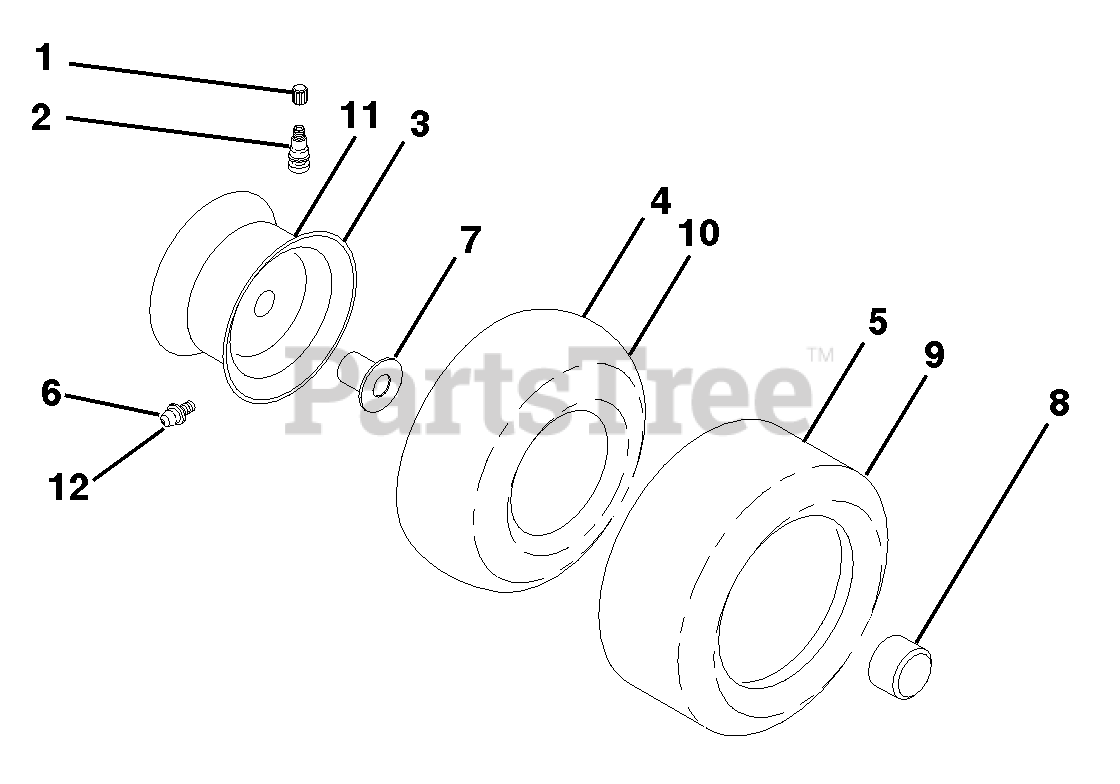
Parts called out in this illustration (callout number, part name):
1	Cap, Valve, Tire
2	Stem, Valve
3	Rim Assembly, Front
4	Tube, Front
5	Tire, Front
6	Fitting, Grease
7	Bearing, Flange
8	Cap, Hub, Axle Blk.
9	Tire, Rear
10	Tube, Rear
11	Rim Assembly, Rear
12	Fitting, Grease
